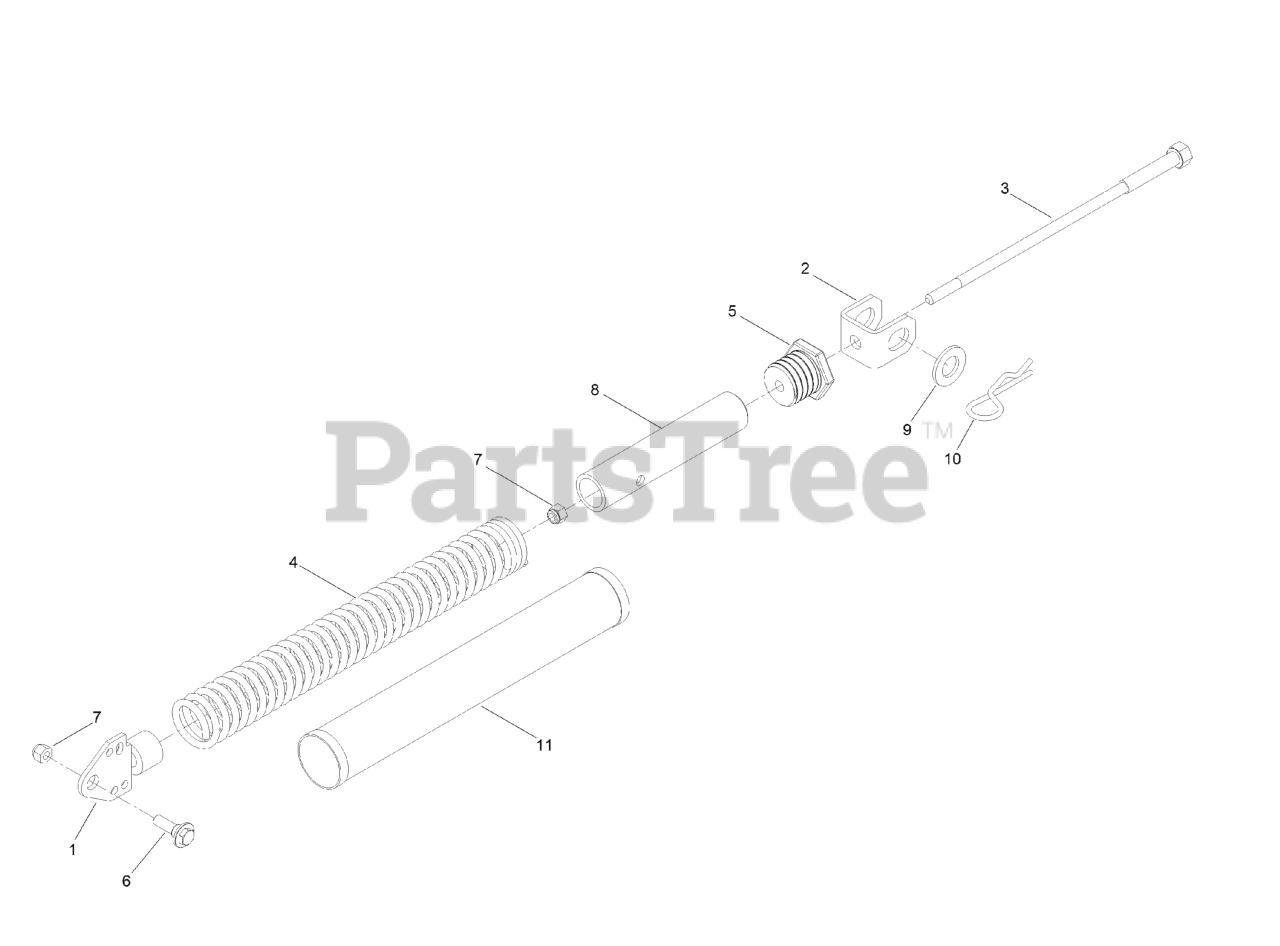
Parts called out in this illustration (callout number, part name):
1	TENSIONER-SPRING
2	MOUNT-LIFT ASSIST, DECK
3	SHAFT-ADJUSTMENT, SPRING
4	SPRING-EXTENSION
5	PLUG-ADJUSTER, SPRING
6	SCREW-SHOULDER, HWH
7	NUT-LOCK, NI
8	SPRING-TUBE
9	WASHER-FLAT
10	PIN-CUT HEIGHT
11	COVER-SPRING, DECK
